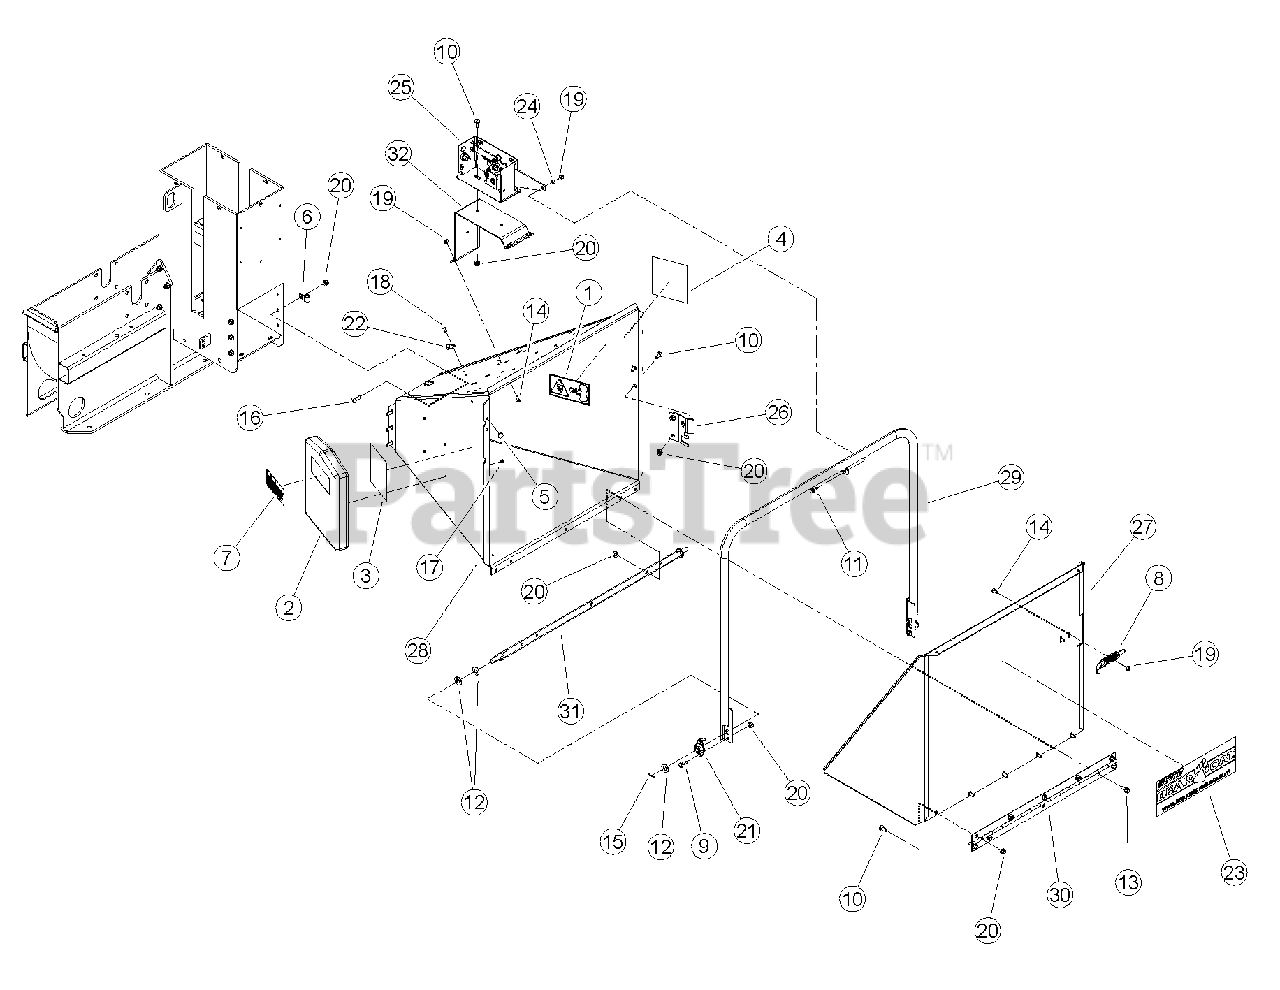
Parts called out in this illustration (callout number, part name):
1	DECAL, BLADE DANGER ISO
2	CONTAINER, INSTR. MANUAL
3	DECAL, FEED POSITION
4	DECAL, FEED POSITION
5	BUMPER, RUBBER
6	CLAMP, 9/16 COATED
7	DECAL, MUTILINGUAL MANUAL
8	LATCH, RH HINGE
9	BOLT, 3/8 X 1 HEX HD GR5 ZP
10	BOLT, 3/8 X 1 GR5 CRG NC ZP
11	BOLT, 5/16 X 1 FLANGE NC
12	WASHER, 5/8" SAE FLAT ZP
13	BOLT, 3/8 X 1 FLANGE NC
14	BOLT, 5/16 X 3/4 GR5 CRG NC ZP
15	PIN, 1/8 X 1.00 ZP COTTER
16	BOLT, 3/8 X 1-1/4 GR5 CRG NC ZP
17	RIVET, AL BLIND 1/4 X 1/2 DOME HEAD
18	RIVET, AL BLIND 1/4 X 3/4 DOME HEAD
19	NUT, 5/16-18 NYLOCK-FLANGE
20	NUT, 3/8-16 NYLOCK FLANGE
21	BEARING, SIDE FLANGE MOUNT 5/8"
22	CLAMP, CABLE MOUNT
23	DECAL, BEARCAT WEB
24	SPACER, IDLER PIVOT
25	ASSEMBLY, SWITCH BOX
26	PLATE, TRAY STOP
27	WELDMENT, CHUTE EXTENSION TRAY
28	WELDMENT, BIG CHIPPER CHUTE
29	WELDMENT, CONTROL ARM
30	HINGE, EXTENSION TRAY
31	WELDMENT, CONTROL PIVOT
32	MOUNT, SWITCH BOX
